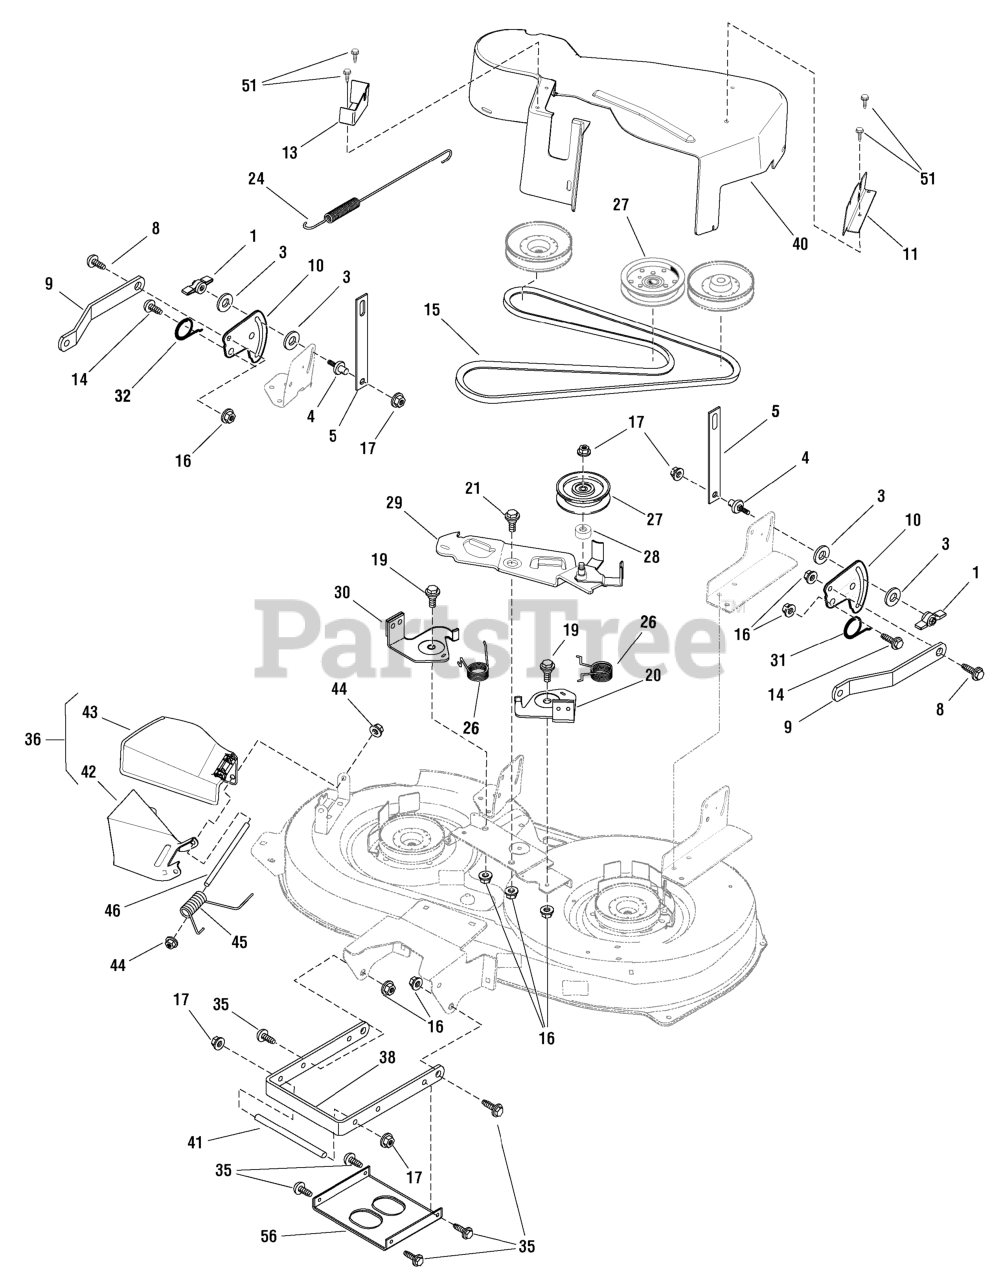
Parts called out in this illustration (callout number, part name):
1	KNOB (5/16-18 nut enclosed)
3	FRICTION PAD
4	PIN, Hanger, 3/8-16 x 1-1/4
5	LINK, Lift (LT)
8	BOLT, Shoulder, 3/8-16 x 1
9	BRACKET, Suspension
10	PLATE SUSPENSION
11	PLATE, Guard, L.H.
13	PLATE, Guard, R.H.
14	BOLT, Shoulder 3/8-16 x 1
15	BELT, V Mower Drive 42"
16	NUT, Hex Flange, 3/8-16
17	NUT, Flange, 3/8-16
19	BOLT, Shoulder, 3/8-16 x 5/8
20	BRAKE ASSEMBLY, L.H.
21	WASHER, Flat, 3/4
24	SPRING, Extension
26	SPRING, Torsion Brake
27	PULLEY, Idler, 4"
28	SPACER, 1/2in to 17mm
29	IDLER ARM ASSEMBLY, 42"
30	BRAKE ASSEMBLY, R.H.
31	SPRING, Torsion Left
32	SPRING, Torsion Right
35	CAPSCREW, 5/16-18 x 3/4
36	DEFLECTOR ASSEMBLY
38	BRACKET, Front Suspension
40	COVER, Deck 42"
41	ROD HANGER
42	SUPPORT, Deflector
43	DEFLECTOR, Chute
44	CAP, Push On
45	SPRING, Torsion
46	ROD, Deflector
49	NUT, Flange, 5/16-18
51	SCREW, Hex, 1/4 x 1/2
54	SCREW, Guide
55	GUIDE, Belt
56	STIFFENER
